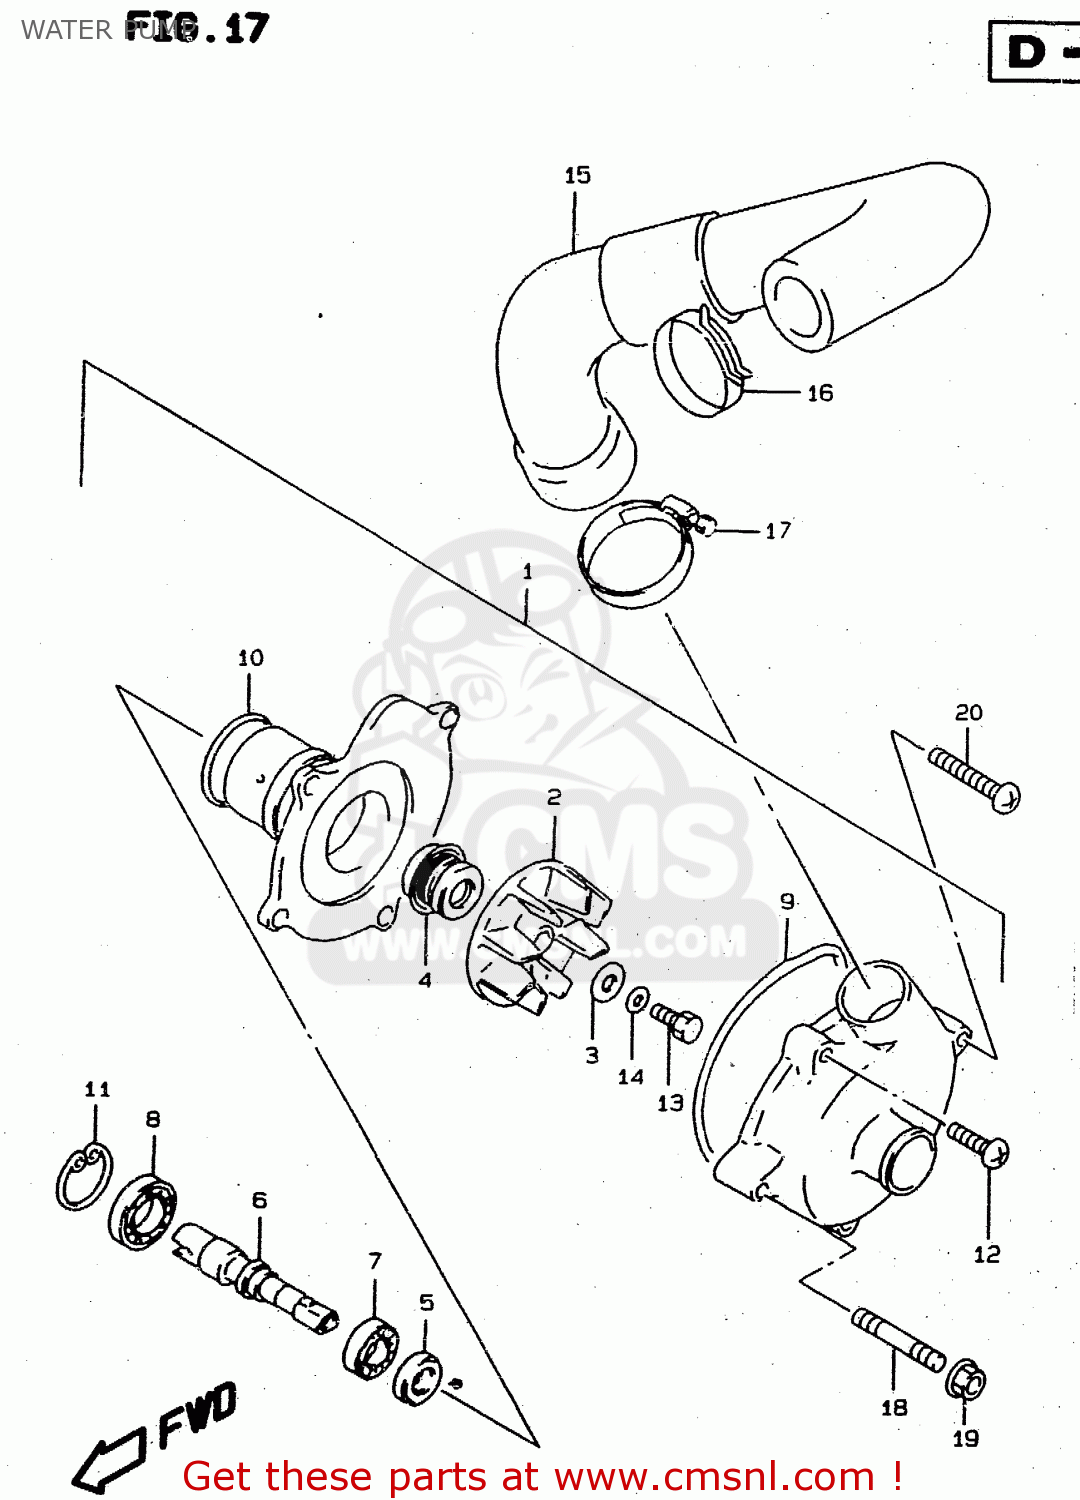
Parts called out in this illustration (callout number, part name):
1	PUMP ASSY,WATER
2	IMPELLER
3	GASKET(6X15X2.2) (NAS)
4	SEAL,MECHANICAL
5	SEAL,OIL(10X21X5)
6	SHAFT
7	BEARING
8	BEARING(12X28X8)
9	O RING
10	O RING,WATER PUMP HOLDER
11	CIRCLIP
12	SCREW 6X16
13	BOLT(6X13)
14	WASHER
15	HOSE,WATER PUMP OUTLET
16	CLAMP
17	CLAMP
18	BOLT,STUD
19	NUT
20	SCREW
